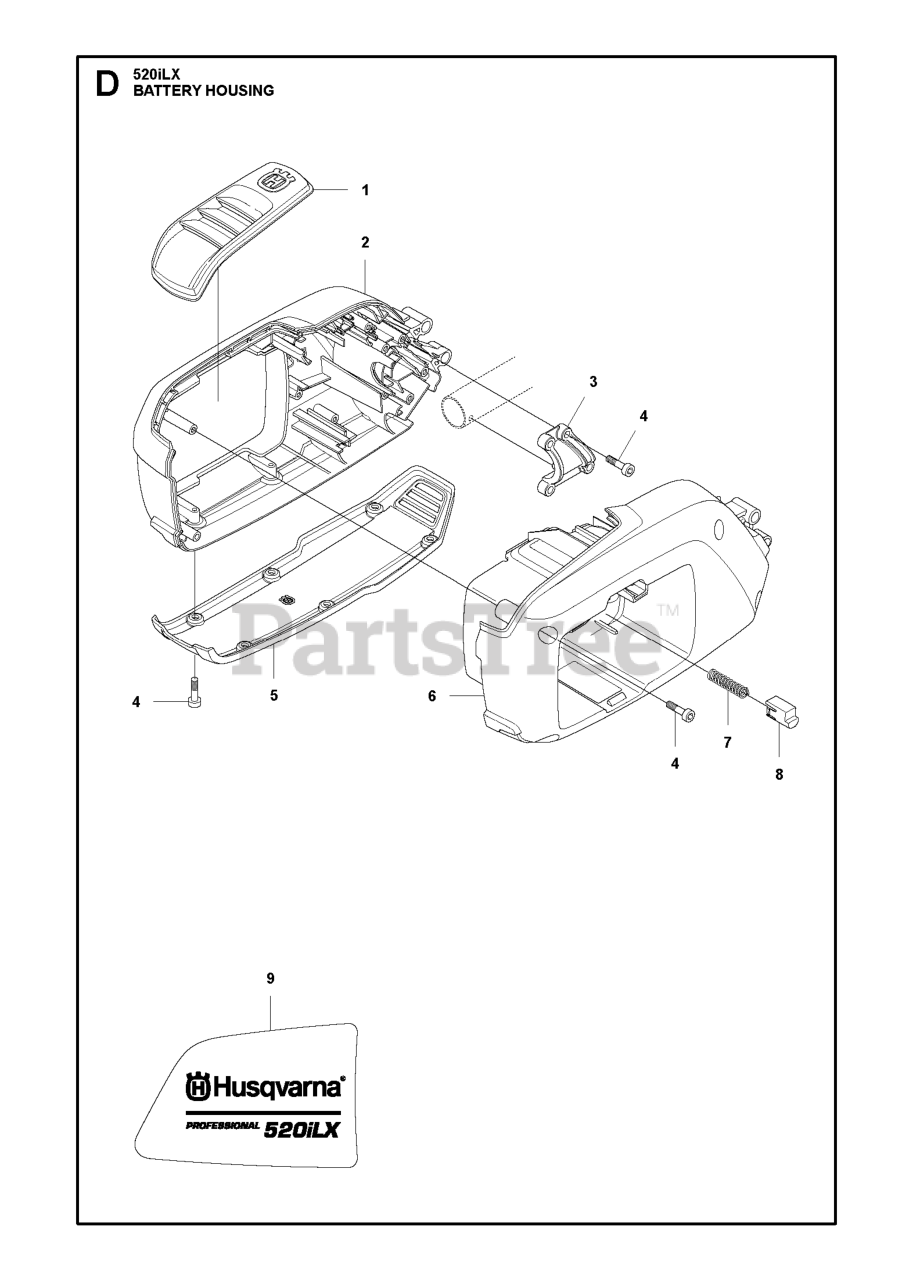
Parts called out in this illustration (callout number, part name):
2	HOUSING LEFT
4	SCREW
5	SKID PLATE
6	HOUSING RIGHT
7	SPRING PUSH OUT
8	PUSH BUTTON
9	DECAL PRODUCT 520ILX
